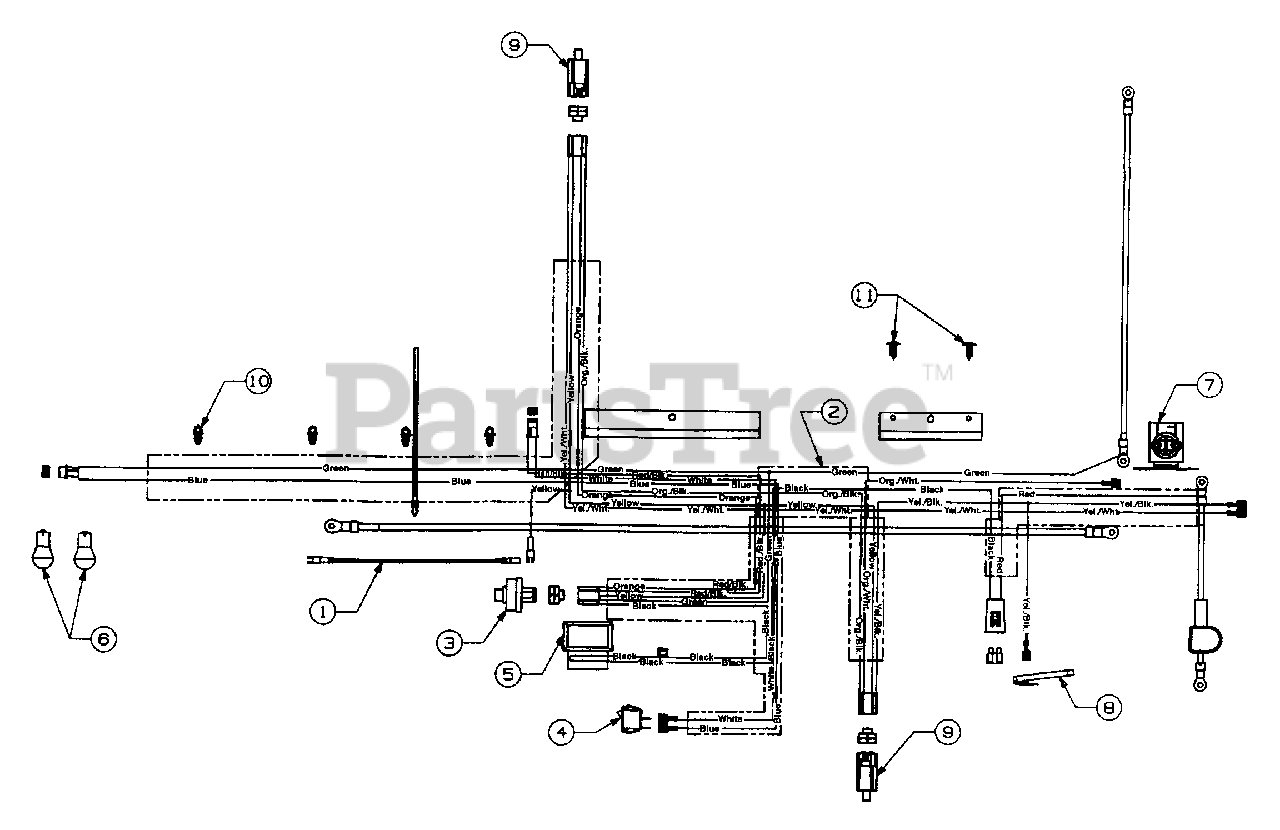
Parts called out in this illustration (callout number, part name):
1	Harness Adapter (Mag.)
2	Wire Harness
3	Ignition Switch
4	Light Switch
5	Ammeter
6	Bulb (Headlight)
7	Solenoid
8	Spring Switch (Reverse)
9	Safety Switch (Clutch)
10	Wire Retainer Clip
